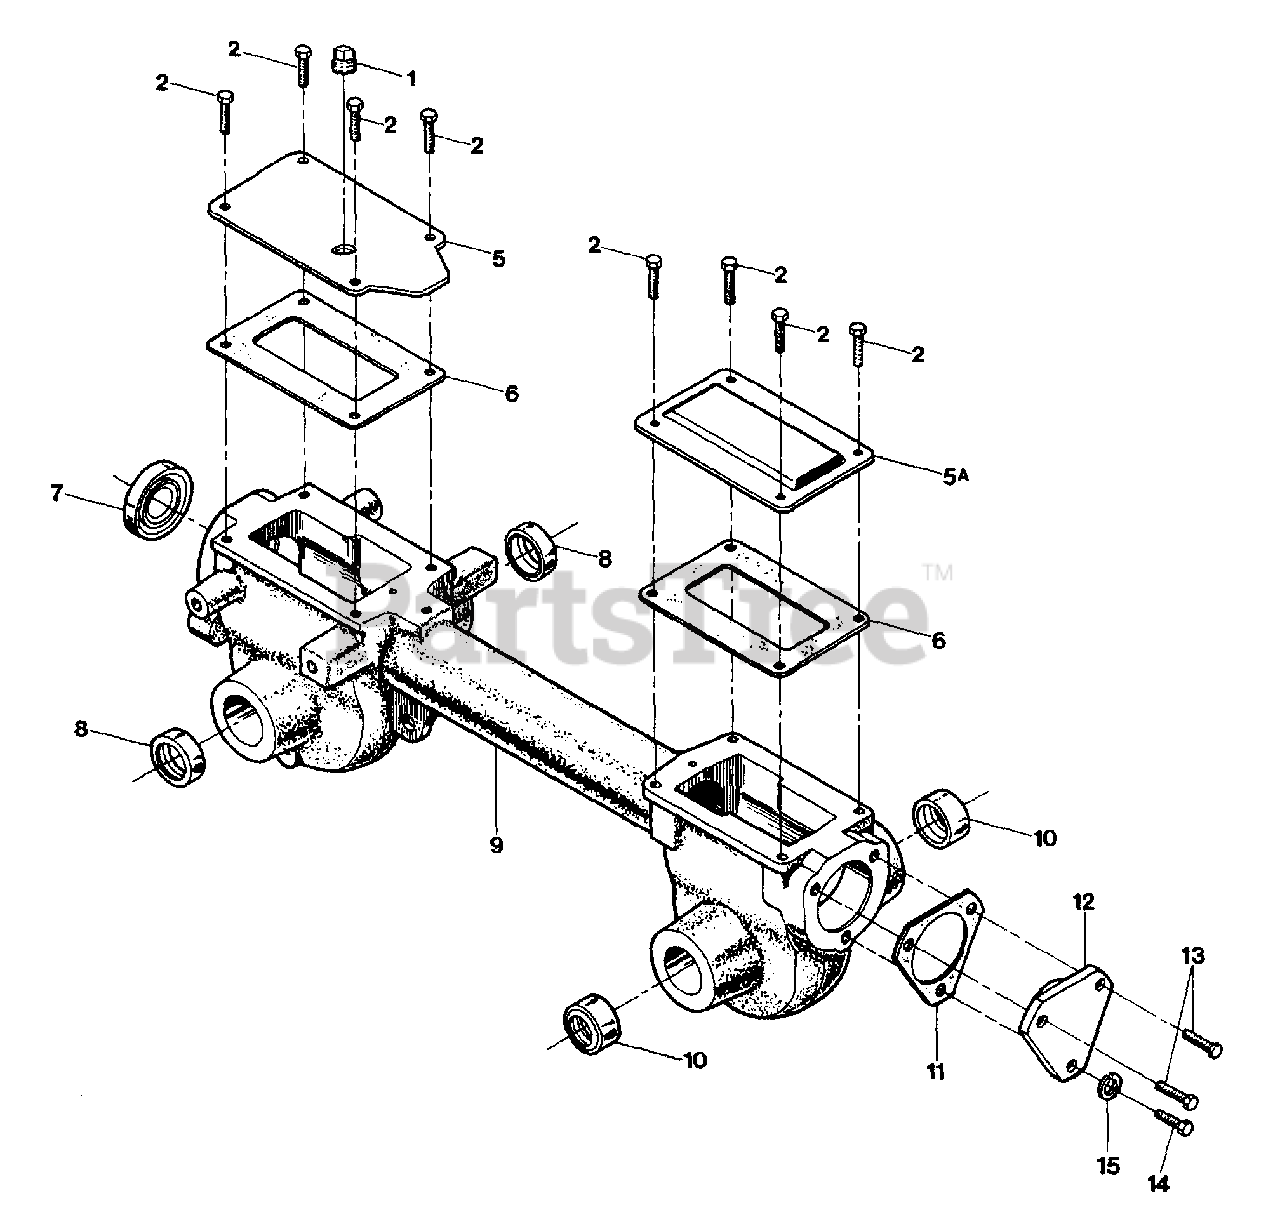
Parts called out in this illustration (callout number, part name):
1	Plug, Transmission Oil Fill
2	Flange Screw, 5/16-18 x 5/8, Grade 5
5	Front Cover, Transmission
5A	Rear Cover, Transmission
6	Gasket, Housing Cover
7	Oil Seal, Drive Shaft
8	Oil Seal, Wheel Shaft
9	Transmission Housing Assy.
10	Oil Seal, Tine Shaft
11	Bearing Cap Gasket, .010" thick
12	Rear Bearing Cap
13	Flange Screw, 5/16-18 x 1
14	Flange Screw, 5/16-18 x 3/4
15	Lockwasher, 5/16
